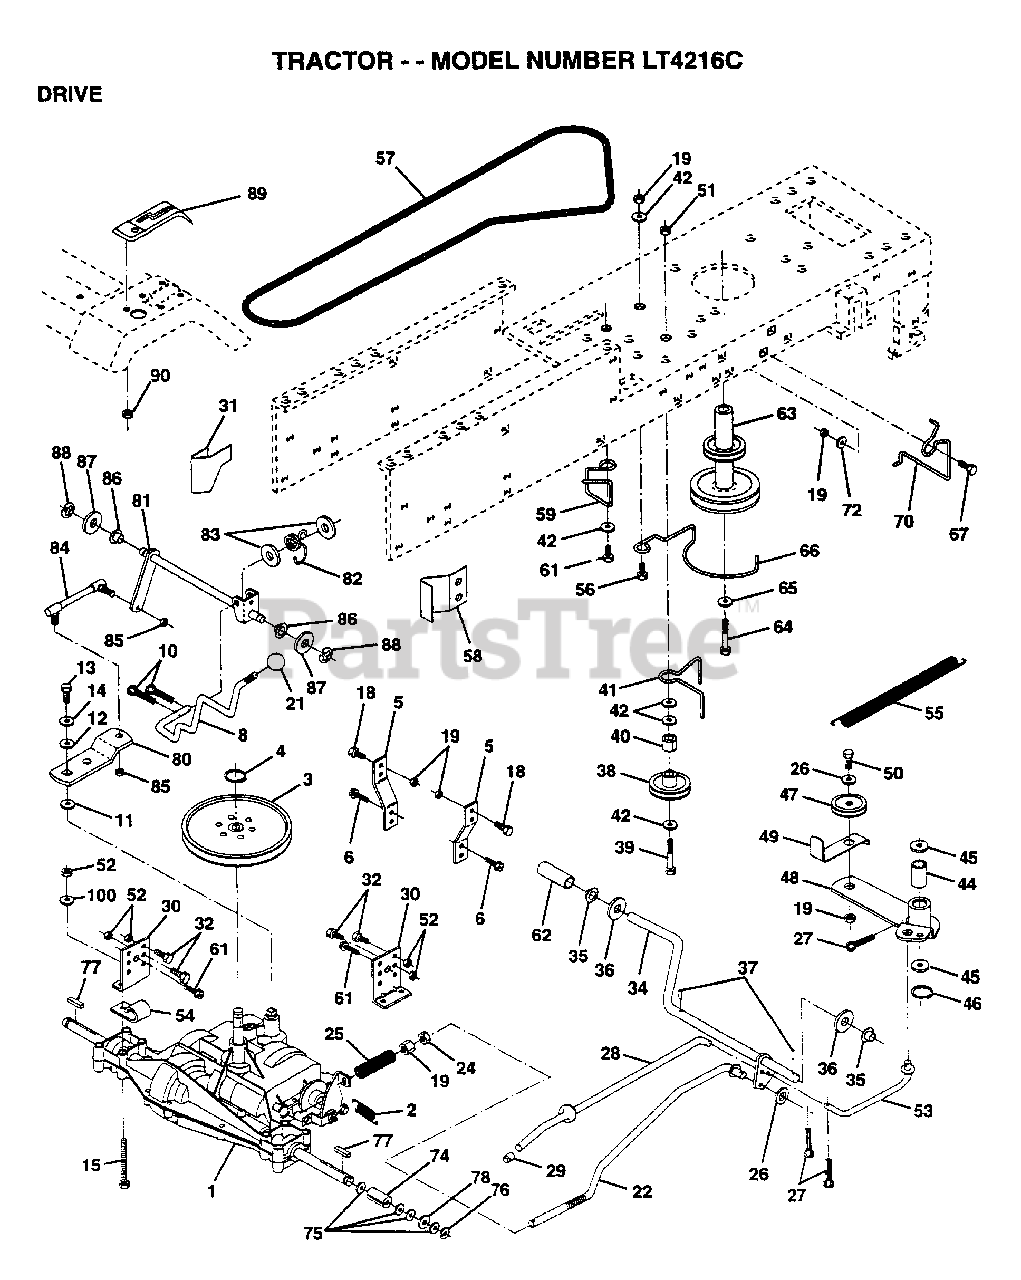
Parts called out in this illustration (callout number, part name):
2	SPRING.BRAKE.RETU
3	PULLEY TRANS
5	STRAP TORQUE
6	SCREW
8	ROD SHIFT FEND LT
10	PIN COTTER 1/8
11	WASH-SHFT PLT LT
12	WASHER
13	BOLT.1/4-28.W/PAT
14	LOCKWASHER
15	BOLT HEX
18	BOLT
19	NUT
21	KNOB T (1/2-HOLE)
22	BRAKE ROD
24	NUT
25	SPRING ROD LT
26	WASHER
27	COTTER PIN
28	ROD.BRAKE.PARK.LT
29	PLUNGER CAP T
30	TRANSAXLE MTG BKT
31	"KEEPER,BELT LH T"
32	BOLT
35	NYLON BEARING
36	WASHER LT
38	PULLEY.IDLER.FLAT
39	BOLT
40	SPACER T
41	BELT KEEPER LT
42	WASHER
44	"LY, BEARING"
45	WASHER LT
46	KLIP RING
48	ARM IDLER
49	RETAIN BELT
53	"LINK, CLUTCH T"
54	CLIP T
55	"SPRING, RETURN LT"
58	"KEEPER,BELT RH T"
59	KEEPER BELT CNTSP
61	SCREW
62	PEDAL COVER T
63	PULLEY.ENGINE
64	BOLT
65	LOCKWASHER
66	KEEPER.BELT.ENG.L
67	BOLT
70	KEEPER BELT ENG
72	WASHER
74	SPACER LT
75	WASHER
76	E-RING LT
77	SQUARE KEY
78	WASHER
80	ARM SHIFT TRANS
81	SHAFT ASM.SHIFT
82	"SPRING,TORSION"
83	WASHER
84	TIE ROD
85	NUT 1/4-28
86	BUSHING
87	WASHER D
88	KLIP RING
90	NUT
100	WASHER M
